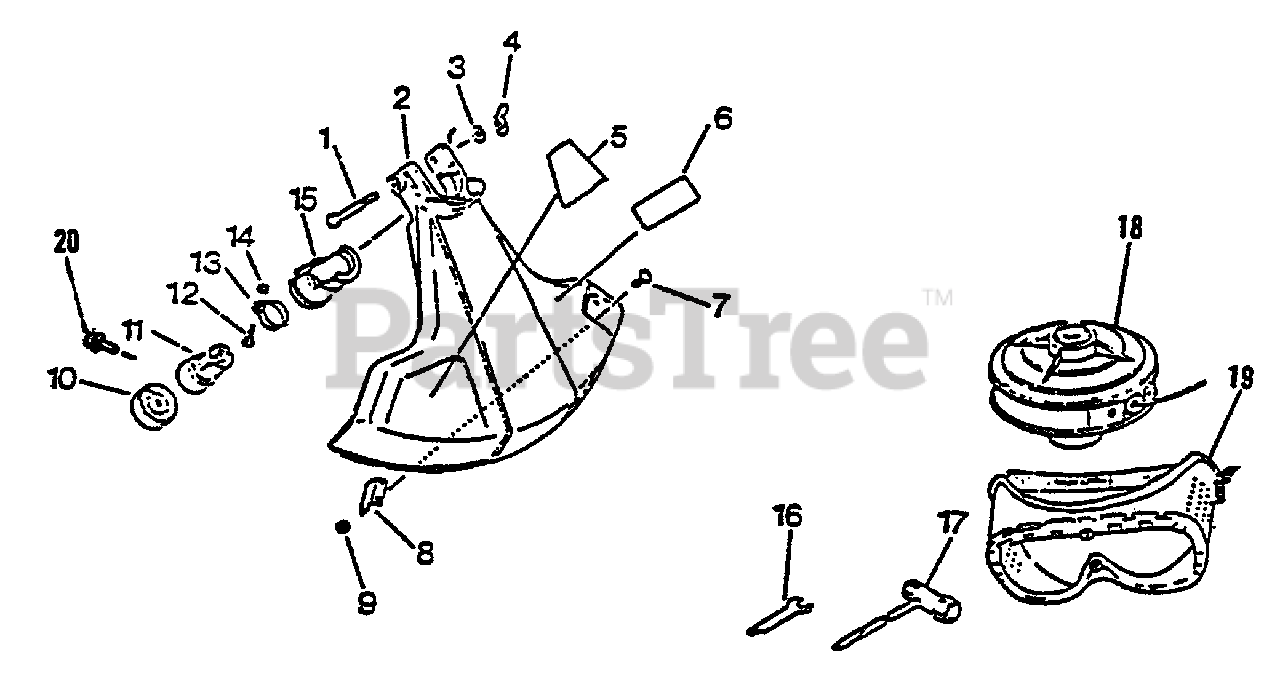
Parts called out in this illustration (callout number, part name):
1	BOLT - 6×50
2	DEBRIS SHIELD KIT
3	WASHER 6.5×11.5×0.8
4	NUT, WING 6
5	LABEL, CAUTION
6	LABEL, ECHO
7	SCREW 5×16
8	CUTTER, LINE
9	NUT M5
10	PLATE, ADAPTER - UPPER
11	GEAR CASE ASSY
12	BOLT M5×10
14	NUT M5
15	BRACKET, BEARING CASE
17	WRENCH
18	KNIFE, TRIMMER LINE
20	SCREW 4×10
